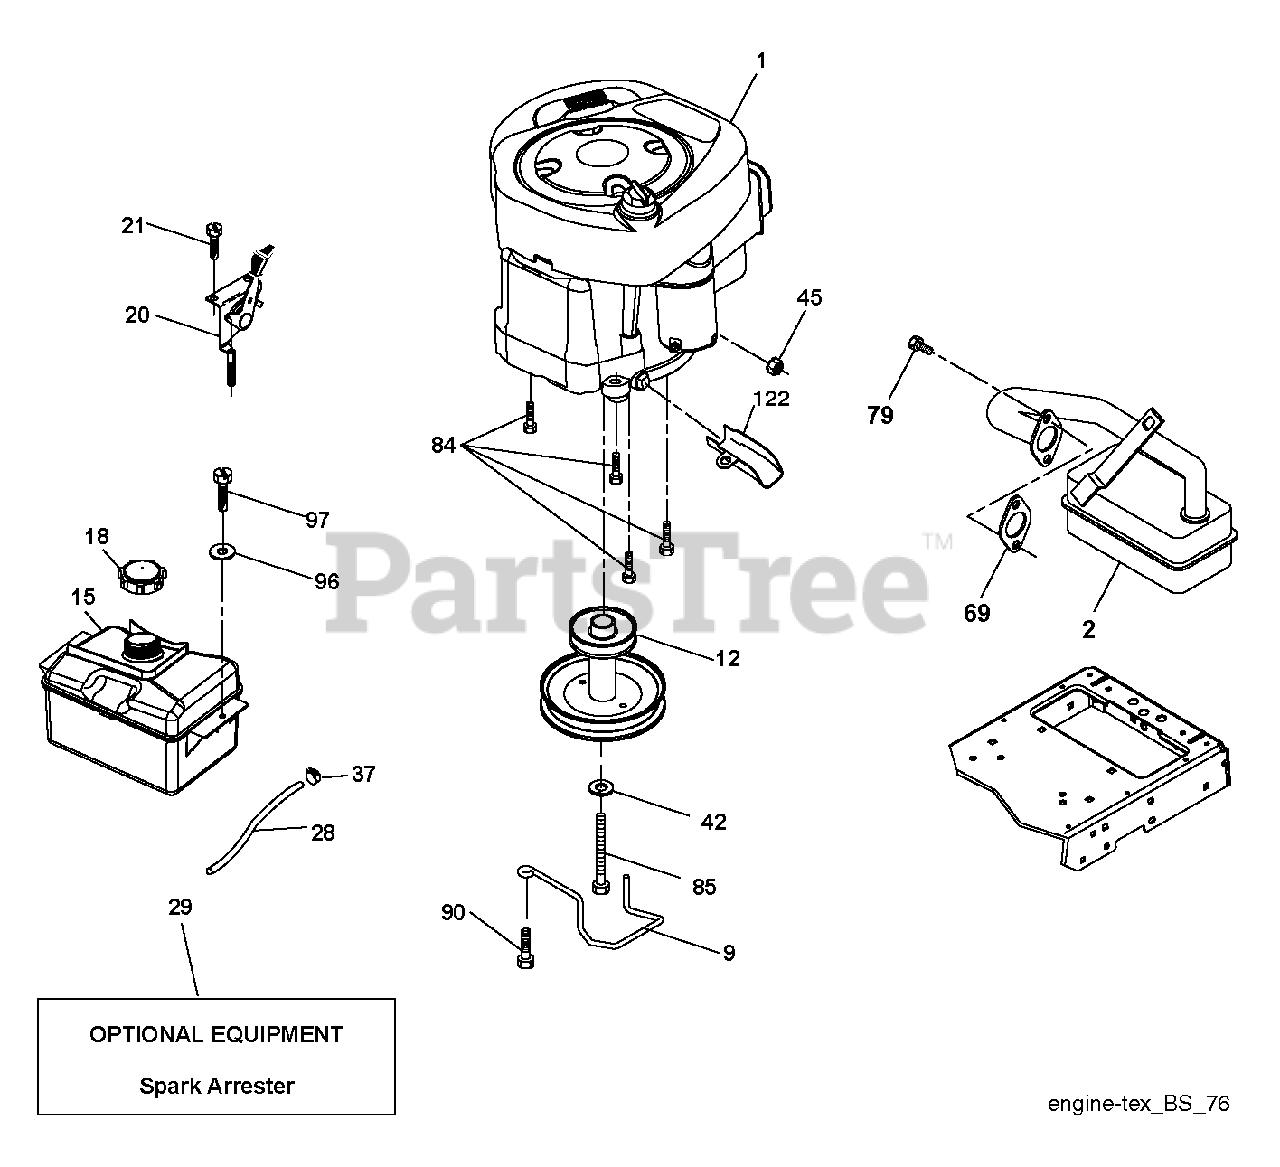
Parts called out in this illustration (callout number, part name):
2	MUFFLER.LT.BRIGGS.14HP.IC/OHV
9	KEEPER.BELT.ENGINE.3.25 (3 2)
12	PULLEY ENGINE
15	FUEL.TANK.ASM.NON-EPA
18	CAP ASM.FUEL.2.25"FR.
20	CONTROL.TH/CK.C.
21	SCREW.#10 X 0.750.BOS
28	LINE.FUEL.20
29	KIT.SPARK ARRESTOR 794945 B&S
37	HOSE CLAMP
42	LOCKWASHER
45	NUT
69	REPL BY 532 27 22-93
79	SCREW.SOCKET HD.5/16-1
84	SCREW.3/8-16
85	BOLT HEX 7/16-20X4-1/4"
90	SCREW 3/8-16X1
97	SCREW HEXWSHR 1/4-20X3/4
122	EXTENSION DRAIN OIL
